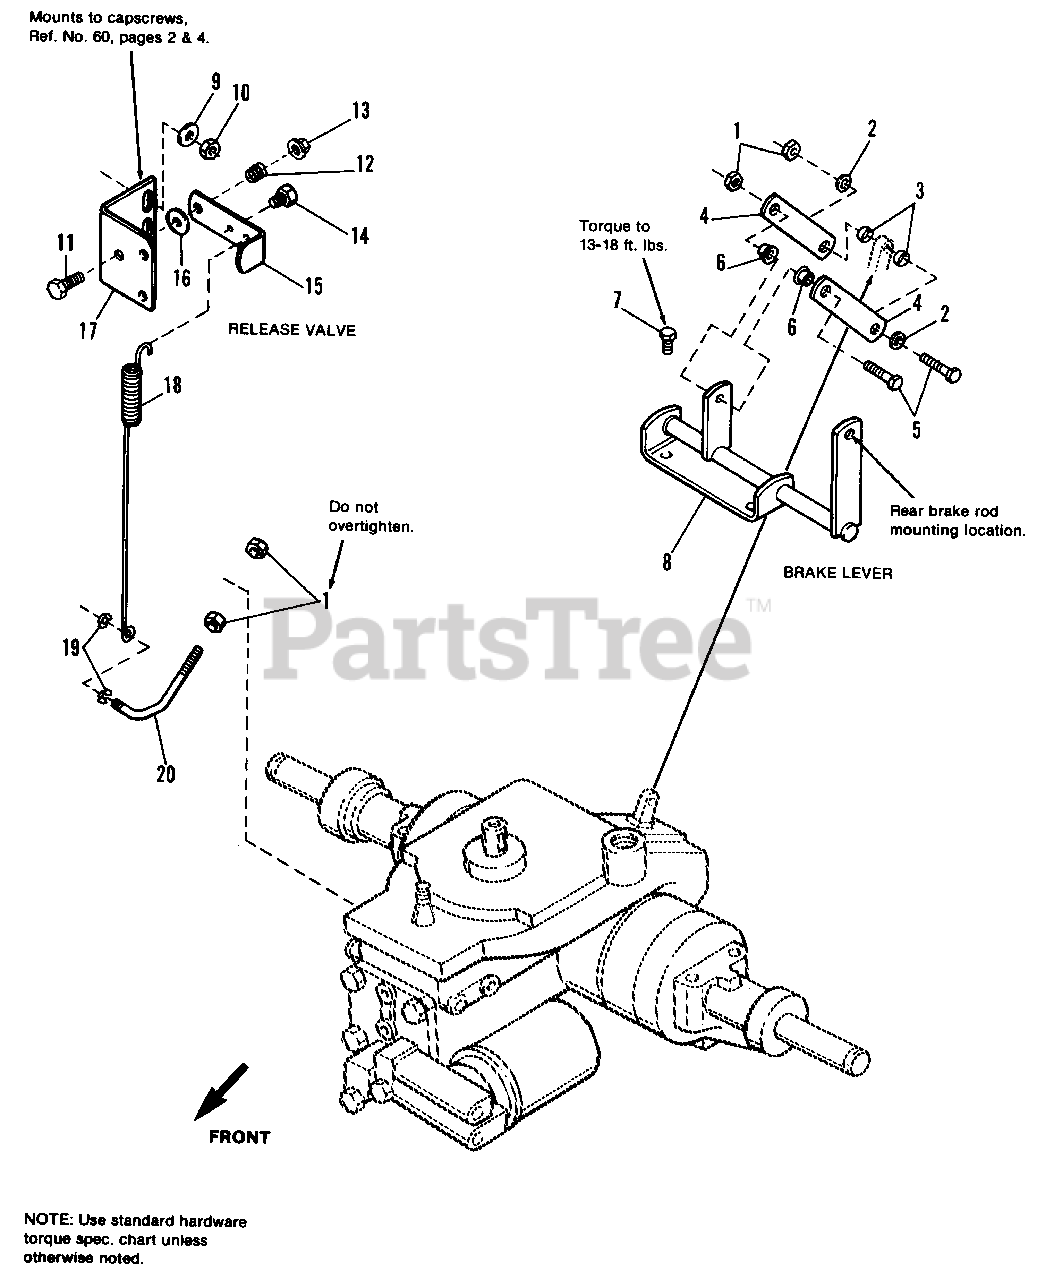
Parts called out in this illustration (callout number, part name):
1	NUT, Hex Lock, 1/4-20
2	WASHER, Flat
4	BRACKET, Brake Clevis
5	CAPSCREW, 1/4-20 x 1-1/4
6	SPACER, Shoulder
7	CAPSCREW, 5/16-18 x 5/8
8	BRACKET ASSY., Brake Lever
10	NUT, Hex, 5/16-18
11	CAPSCREW, Hex Hd., 1/4-20 x 1-1/4
12	SPRING, Compression
13	NUT, Hex, Flange Lock, 1/4-20
14	SCREW, Taptite, 1/4-20 x 3/8
15	LEVER, Release Valve
16	WASHER, Nylon
17	BRACKET ASSY., Release Valve
18	SPRING, Tension
20	LEVER, Hydro Release Valve
